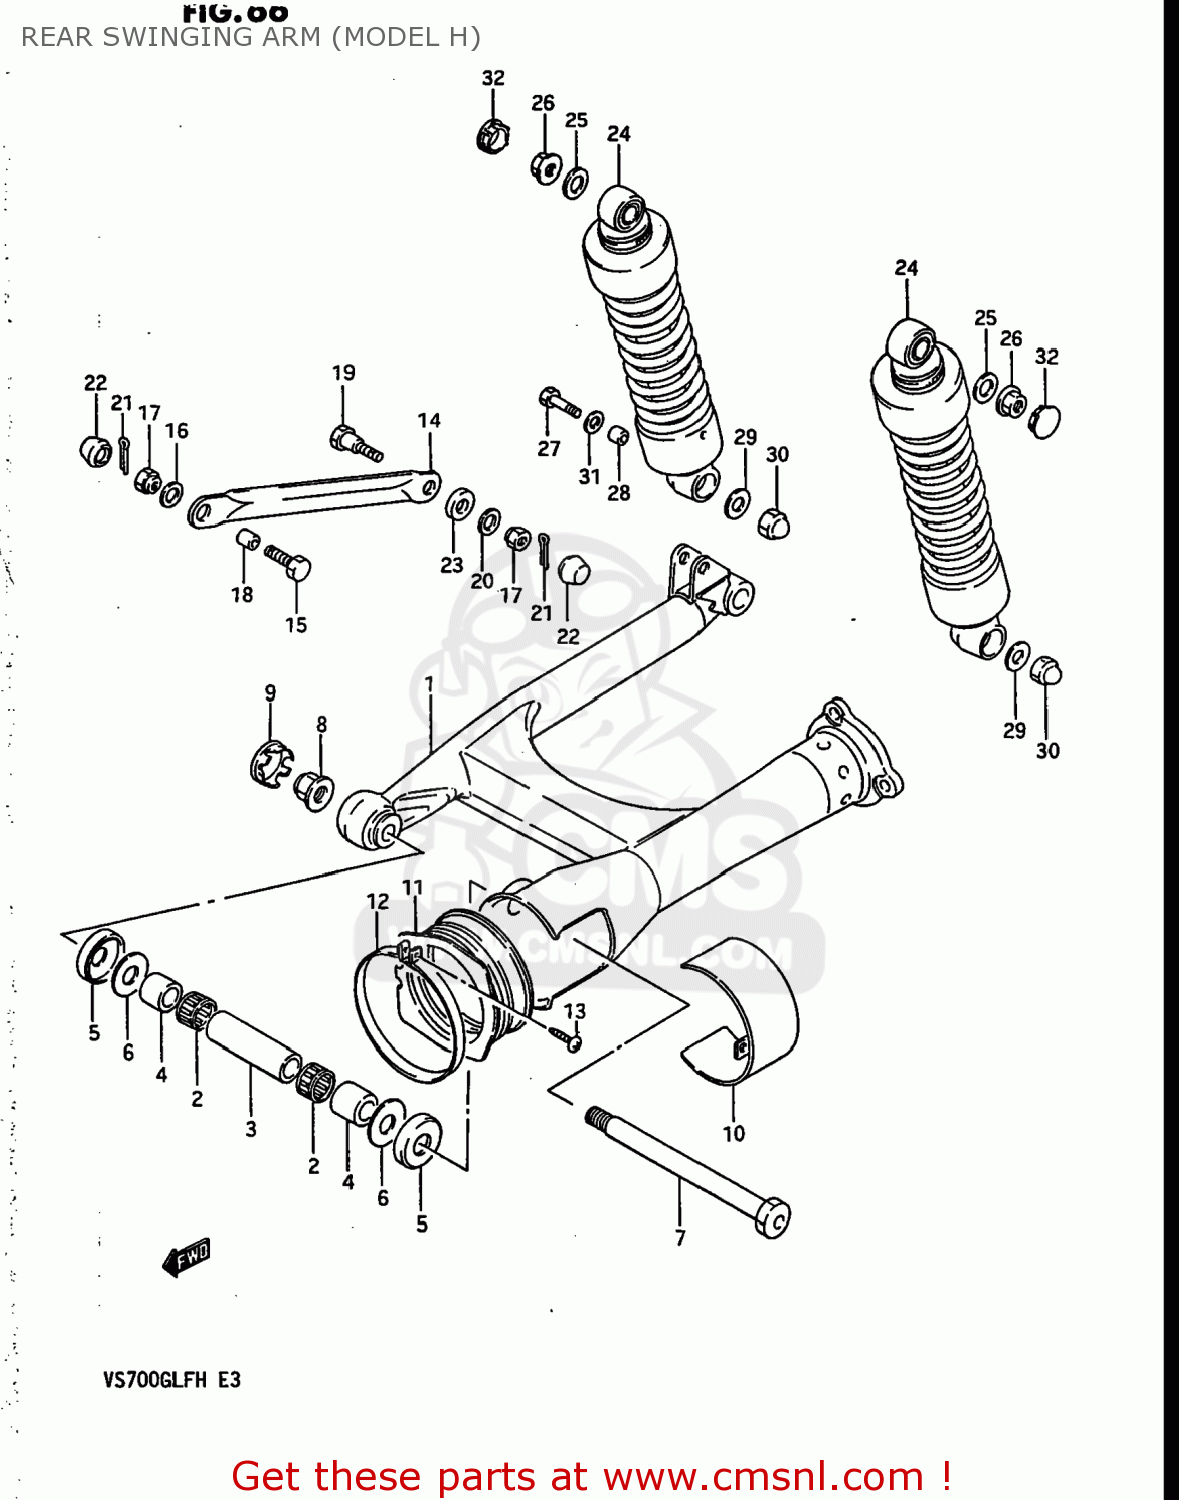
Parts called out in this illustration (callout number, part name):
1	SWING ARM ASSEMBLY,REAR
2	BEARING(22X29X20)
3	SPACER,REAR SWING ARM PIVOT
4	SPACER,RR SWGARM PIVOT
5	CVR,RR SWGARM DUST SEAL(OD:40)
6	WASHER
7	SHAFT,RR SWINGINGARM PIVOT
8	NUT
9	CAP,REAR SWING ARM PIVOT
10	COVER,REAR SWING ARM PIVOT
11	BOOT,PROPELLER SHAFT
12	CLAMP
13	SCREW 4X25
14	TORQUE LINK,REAR
15	BOLT(10X28)
16	WASHER
17	NUT
18	SPACER
19	BOLT(10X41)
20	WASHER (10X20X2.3)
21	COTTER PIN
22	CAP
23	CUSHION
24	ABSORBER ASSEMBLY,REAR SHOCK
25	WASHER
26	NUT
27	BOLT(10X39)
28	SPACER (10.2X14X20.7)
29	WASHER
30	NUT, LOWER LH
31	WASHER 10MM
32	CAP,FRAME HANDLE GRIP
